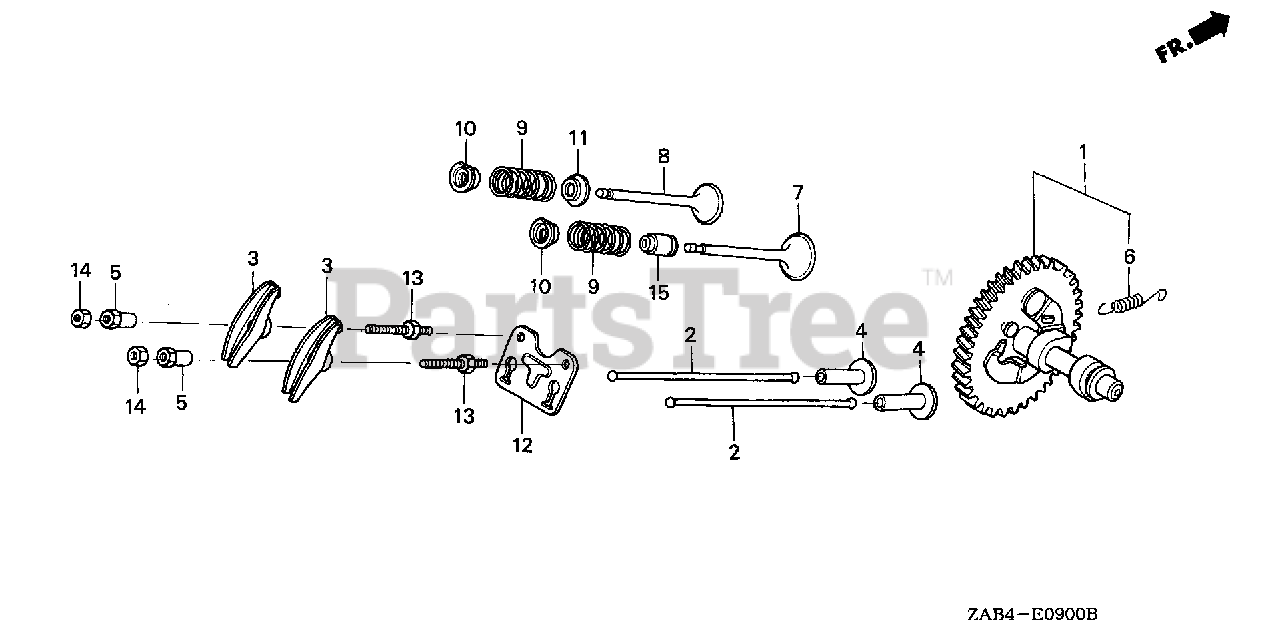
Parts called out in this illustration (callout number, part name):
1	CAMSHAFT ASSY.
2	ROD, PUSH
3	ARM, VALVE ROCKER
4	LIFTER, VALVE
5	PIVOT, ROCKER ARM
6	SPRING, WEIGHT RETURN
7	VALVE, IN. (GAS)
8	VALVE, EX. (GAS)
9	SPRING, VALVE
10	RETAINER, IN. VALVE SPRING
11	SEAT, VALVE SPRING
12	PLATE, PUSH ROD GUIDE
13	BOLT, PIVOT (8MM)
14	NUT, PIVOT ADJ.
15	SEAL, VALVE STEM
